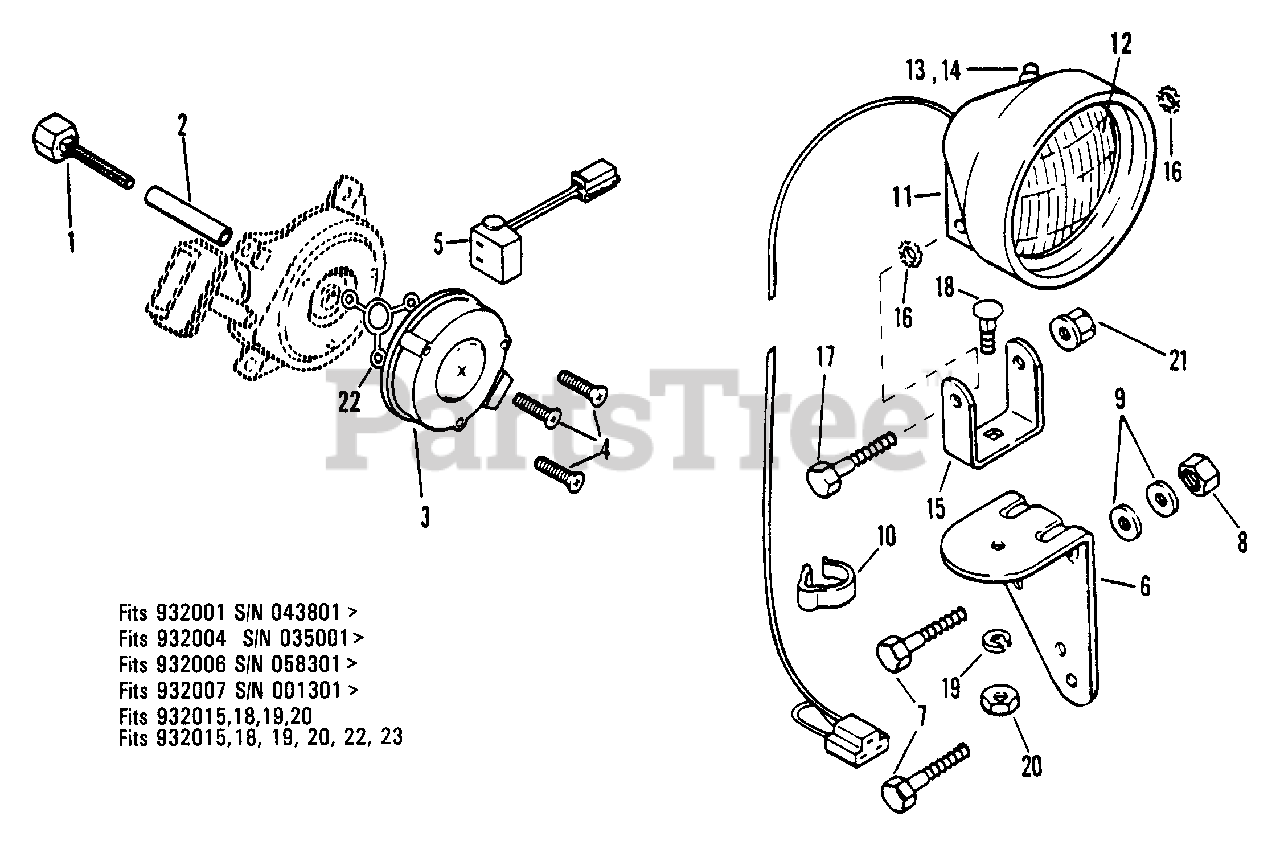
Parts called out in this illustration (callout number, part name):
2	Centering Tube
3	Alternator
4	SCR-TAP 8-18X1.12 CRFH PL B
4	SCR-TAP 8-18X1.25 CRFH PL B
5	LIGHTING CONNECTOR
6	HEADLIGHT BRACKET
7	BLT-HEX .25-20X1.75 PL GR2
7	BLT-HEX .25-20X1.25 GR5 YWZC
8	NUT-LK-CTR .250-20 PL
9	WSHR-FL-STL .380X.875X.179 PL
10	CONDUIT CLAMP 2 WIRE
11	HEAD LIGHT ALTERNATE 024562
11	HEADLIGHT ALTERNATE 024570
12	HEAD LIGHT
13	PUSH BUTTON SWITCH
14	SWITCH BOOT
15	U-BRACKET
16	WSHR-LK-EXT .313X.030 PL
17	BLT-HEX .31-18X2.50 PL GR2
18	BLT-RDHDSQNK .31-18X1.00 PL
19	WSHR-LK .312X.097 PL HVY
20	NUT-HEX .31-18 YWZC
21	NUT-FLG. .312-18 PL
22	SPACER-ALTERNATOR
